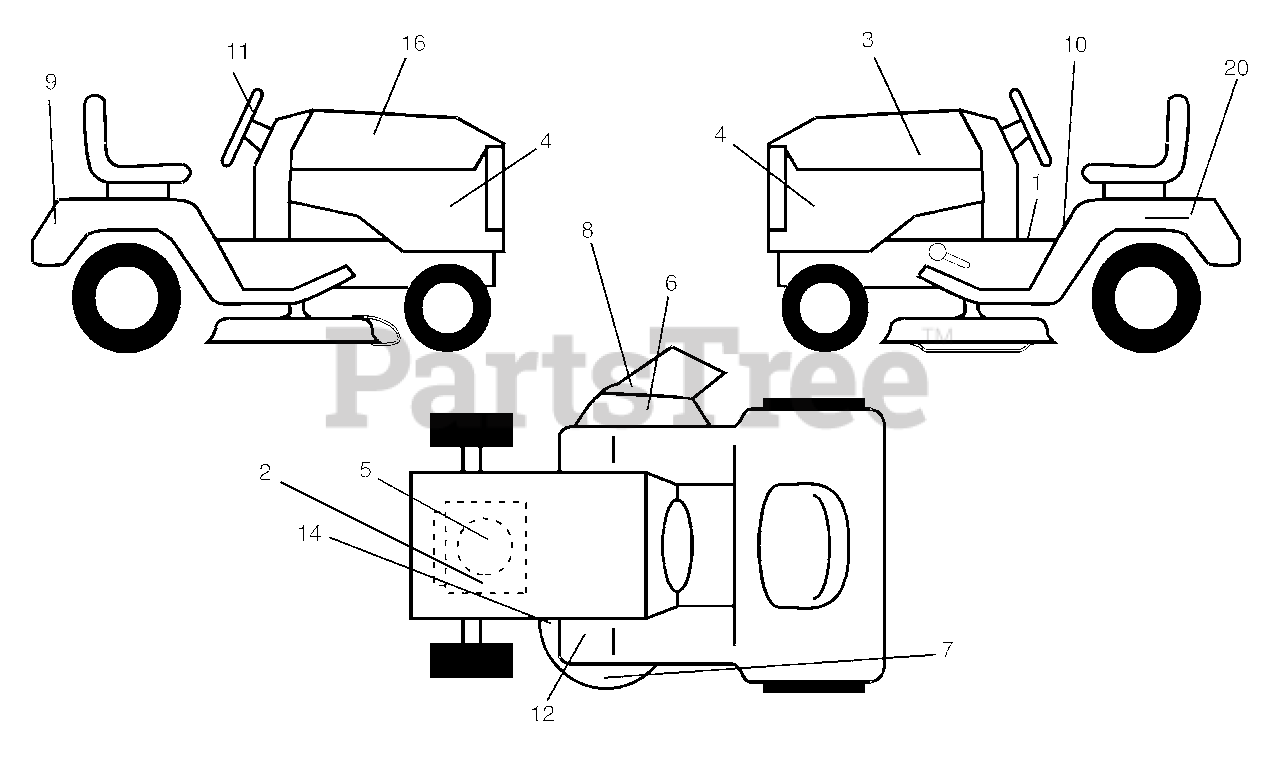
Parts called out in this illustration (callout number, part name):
1	Decal Oper
2	Decal Tec 3 Yr Warranty
3	Decal Hood LH
4	Decal Side Pnl
5	Decal HP Engine
6	Decal Deck "B" 42"
8	Decal Warning Mult-Language
9	Decal Fender Logo
10	Decal Fender Danger
11	Decal Ins Strg Whl
12	Decal Footrest
14	Decal V-Belt Schematic
16	Decal Hood Rh
20	Decal Bat Dan/Psn
